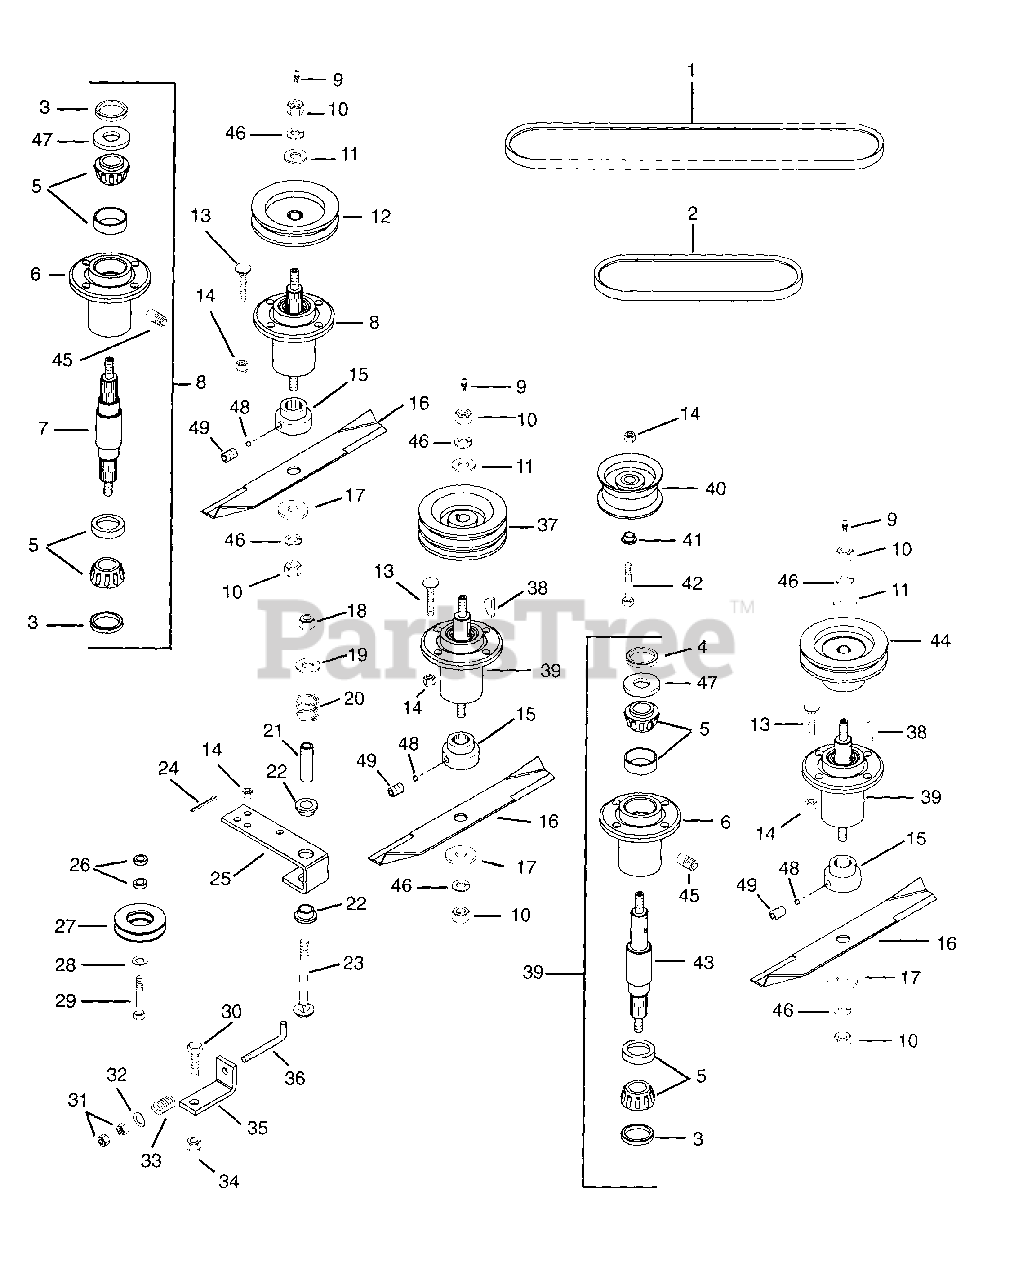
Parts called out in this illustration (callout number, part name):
1	V-Belt Wrapped, Pro 150/50"
2	V-Belt A-Section
3	Seal 1.987 x 1.375 x .313
4	Seal 1.987 x 1.500 x .313
5	Assembly, Bearing Cup & Cone
6	Bearing Housing
7	Shaft, Spindle
8	Service Kit Spindle Assembly
9	Fitting, Lube 1/8
10	Nut-Hex .625-11 Grade 2
11	Washer-Flat-Steel .687 x 1.312 x .150
13	Bolt-Round Head Square Neck .38-16 x 1.375
14	Nut-Locking-Nylon .375-16 Grade 2
16	Blade
17	Washer-Flat-Steel .640 x 1.81 x .250
18	Nut-Locking .50-13
19	Washer-Flat-Steel .531 x 1.250 x .100
20	Spring-Compression .085 x .80 x 1.00
21	Bushing, Steel .560 x .750 x 2.44
22	Bushing-Flange .762 x 1.0 x .580 x 1.48
23	Bolt-Hex .50-13 x 3.50 Grade 5
24	Pin-Cotter .09 x .75
25	Arm, Idler Pivot
26	Bushing .406 x .750 x .188
27	Idler-V 3 x .38
28	Washer-Flat-Steel .375 x 1.125 x .065
29	Bolt-Hex .38-16 x 2.00 Grade 5
30	Bolt-Hex .50-13 x 1.25 Grade 5
31	Nut-Hex .375-16 Grade 2
32	Washer-Flat-Steel .406 x .812 x .065
33	Spring-Compression .125 x .78 x 1.00
34	Nut-Locking-Nylon .50-13 Grade 5
35	Bracket, Belt Tensioner
36	Rod, Idler
38	Key, Woodruff .25 x 1
39	Service Kit Spindle Assembly
40	Pulley-Flat 4.0 x .38
41	Bushing-Sleeve .377 x .503 x .88
42	Bolt-Hex .38-16 x 3.00 Grade 5
43	Shaft, Spindle
45	Relief Fitting
46	Washer-Locking .625 x .156
47	Washer-Hardened-Thrust 1.007 x 1.542 x .062
49	Screw-Set .25-20 x .25
